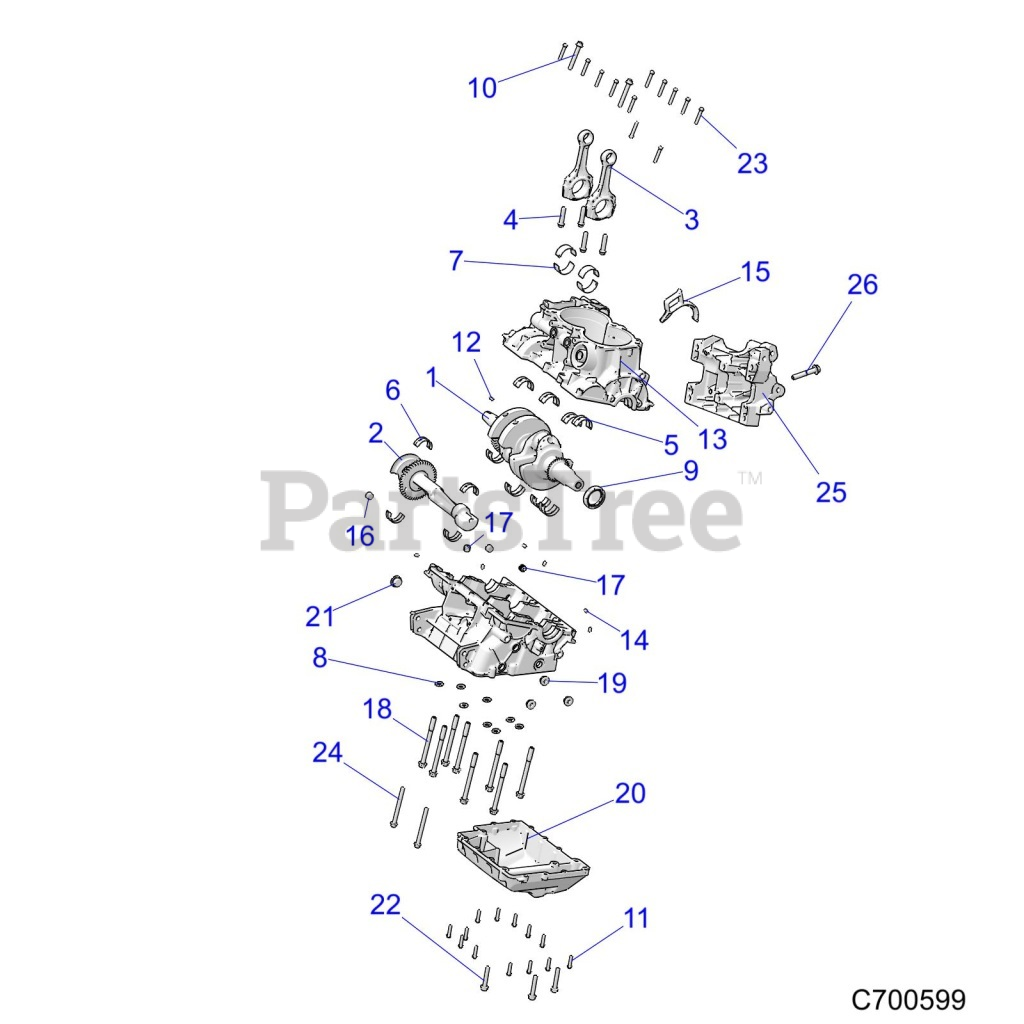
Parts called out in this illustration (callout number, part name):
1	ASM-CRANKSHAFT
2	ASM., BALANCE SHAFT
3	ASM-CONNECTING ROD
4	SCR-ROD,MJ9X1X40-4H6H,12.9
5	BEARING, MAIN, WHITE
5	BEARING, MAIN, BLUE
5	BEARING, MAIN, GREEN
5	BEARING, MAIN, YELLOW
5	BEARING, MAIN, RED
6	BEARING, CONNECTING ROD, WHITE
6	BEARING, CONNECTING ROD, BLUE
6	BEARING, CONNECTING ROD, GREEN
6	BEARING, CONNECTING ROD, YELLOW
7	BEARING, BALANCE SHAFT
9	SEAL-CRANKSHAFT
10	SCR-HXFLG,M8X1.25X60
11	SCR-HXFLG,M6X1.0X25,10.9
12	KEY,WOODRUFF
13	KIT, CRANKCASE
14	PIN, DOWEL
15	DIVERTER, OIL DRAIN
16	PLUG-3/8 NPT,HX/SOC W/SEALANT
17	PLUG-HEX SOCKET,1/4X18,SEALANT
18	SCR-HXFL M10X1.25X115MM 10.9
19	PLUG-HEX SCKT,W/O-RING,M16X1.5
20	COVER, SUMP
21	PLUG-HEX SCKT,W/O-RING,M20X1.5
22	SCR-M8X1.25X50 HX/FL-Y
23	SCR-HXFL-M6X1.0X35 8.8 ZY3
24	SCR-HXFLG,M8X1.25X90
25	BRKT-TRANSJOINT,MACH
26	BOLT-M10X1.5X60MM8.8HEXDRILOCK
